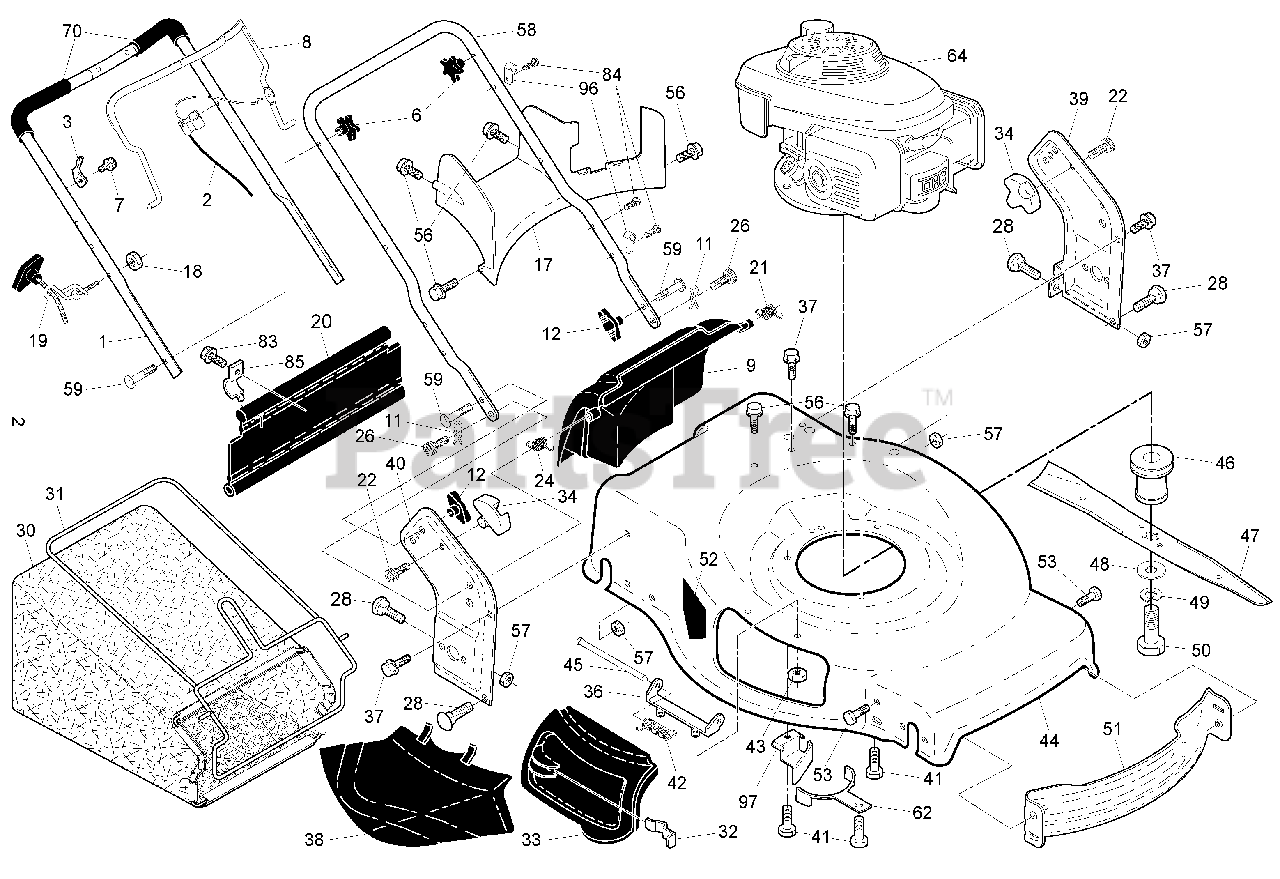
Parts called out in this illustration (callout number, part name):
1	Upper Handle Assembly
2	Cable, Engine Zone Control
3	Bracket, Upstop
6	Handle Knob, Star
7	Screw #10-24 x 1/2
8	Control Bar
9	Rear Door Assembly
11	Hairpin, Door/Handle Pivot
12	Handle Knob, Standard
17	Rear Baffle
18	Keps Locknut 1/4-20
19	Rope Guide
20	Rear Skirt
21	Spring, Rear Door, LH, Black
22	Screw, Panhead, Torx #20
24	Spring, Rear Door, RH, Grey
26	Screw, Rear Door/Handle Pivot
28	Bolt, Carriage 5/16-18 x 5/8
31	Frame, Grass Catcher
32	Latch, Mulcher Door
33	Mulcher Door
34	Bracket, Grassbag
36	Hinge Bracket Assembly
38	Discharge Deflector
39	Handle Bracket, LH
40	Handle Bracket, RH
41	Screw, Dogpoint 3/8-16 x 1-1/8
42	Spring, Torsion
43	Nut, Hex, Nylock
44	Kit, Lawn Mower Housing
45	Rod, Hinge
46	Blade Adapter / Pulley
47	Blade, 22"
48	Washer, Hardened
49	Washer, Helical
50	Screw, Machine, Hex Head 3/8-24 x 1-3/8 Grade 8
51	Front Baffle
52	Decal, Danger
56	Screw, Hex Washer Head #13 x 3/4
58	Lower Handle
59	Handle Bolt
62	Belt Retainer
70	Grip, Foam
83	Screw, Hex Washer Head
84	Fastener, Push
85	Mounting Bracket, Rear Skirt
96	Clip, Cable
97	Belt Keeper
